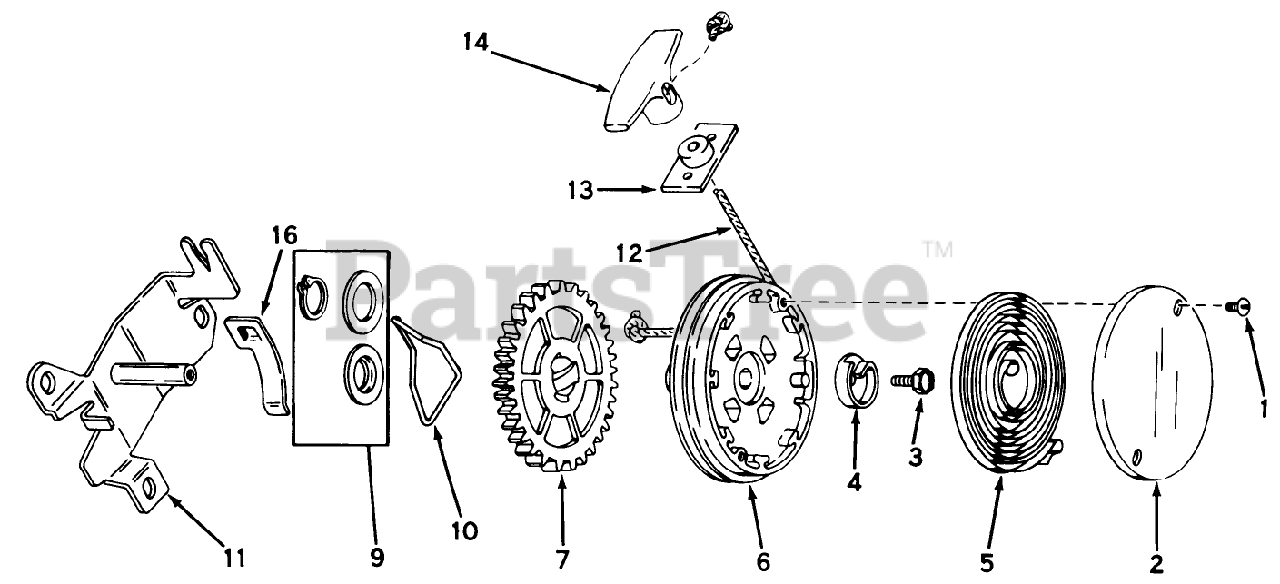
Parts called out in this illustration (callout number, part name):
2	Cover, Spring
3	Screw, Hex Washer Head
4	Hub Spring
5	Spring, Rewind
6	Pulley Assy. (Incl. Ref. #9)
9	Kit, Thrust Wash. & Snap Rg.
11	Bracket Assy. Mounting
12	Rope-Starter
13	Bracket Assy.
14	Handle-Starter
16	Clip Rope
